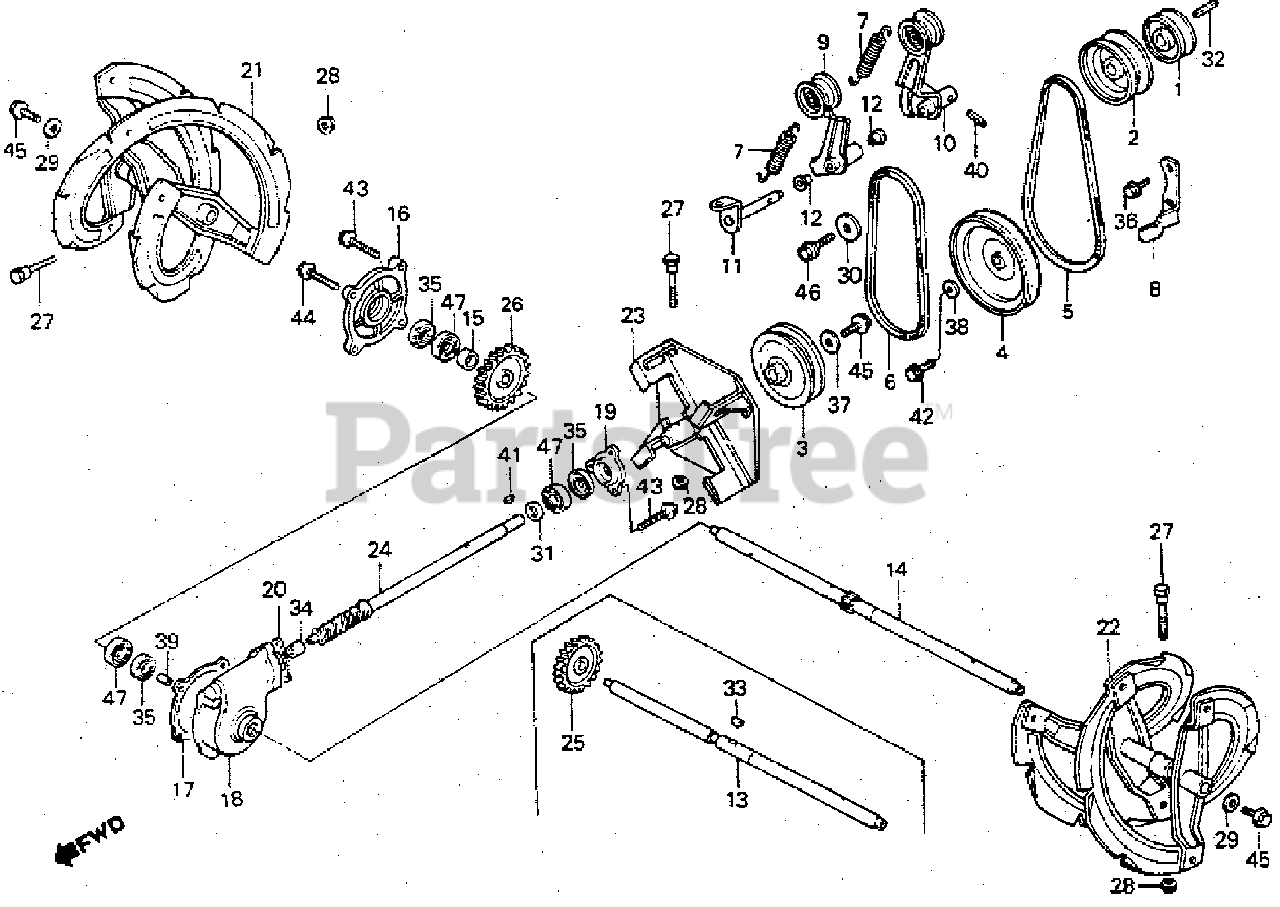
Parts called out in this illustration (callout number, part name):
1	PULLEY, WHEEL DRIVEN (NOT AVAILABLE)
2	PULLEY, AUGER DRIVE
3	PULLEY, AUGER DRIVEN (NOT AVAILABLE)
4	PULLEY, WHEEL DRIVEN (NOT AVAILABLE)
5	V-BELT (31.7)
6	V-BELT (SB-27)
7	SPRING, TENSIONER RETURN
8	STOPPER, BELT
9	ARM, AUGER TENSIONER
10	ARM, TENSIONER
11	SHAFT, TENSIONER (NOT AVAILABLE)
12	BUSH, TENSIONER ARM
13	SHAFT, AUGER
14	SHAFT, AUGER
15	COLLAR, DISTANCE
16	COVER, AUGER TRANSMISSION (NOT AVAILABLE)
17	GASKET, AUGER TRANSMISSION
18	CASE, L. AUGER TRANSMISSION
19	CAP, AUGER CASE (NOT AVAILABLE)
20	GASKET, AUGER CASE
23	BLOWER (12")
23	BLOWER (12") (NOT AVAILABLE)
24	GEAR, DRIVE (NOT AVAILABLE)
25	GEAR, DRIVEN
26	GEAR, DRIVEN (NOT AVAILABLE)
27	BOLT, LOCK
28	NUT, SELF-LOCK (6MM)
29	WASHER (8MM)
30	WASHER, LOCK (8MM)
31	WASHER, THRUST (27X20X1.0)
32	KEY (5X5X33)
33	KEY, SPECIAL WOODRUFF (25X18)
33	KEY, SPECIAL WOODRUFF (25X18) (NOT AVAILABLE)
34	BEARING, NEEDLE (15MM)
35	OIL SEAL (20X32X7)
36	BOLT, HEX. (8X16)
37	WASHER (20MM)
37	WASHER, PLAIN (6MM)
38	WASHER, LOCK (8MM)
38	WASHER, PLAIN (8MM)
39	PIN A, DOWEL (8X14)
40	PIN, SPRING (6X25)
41	KEY, WOODRUFF (16X12)
42	BOLT, FLANGE (6X16)
43	BOLT, FLANGE (6X20)
44	BOLT, FLANGE (6X28)
45	BOLT, FLANGE (8X16)
46	BOLT, FLANGE (8X20)
47	BEARING, RADIAL BALL (6004)
NI	KEY, SPECIAL WOODRUFF (16X12)
NI	KEY, WOODRUFF (16X12)
